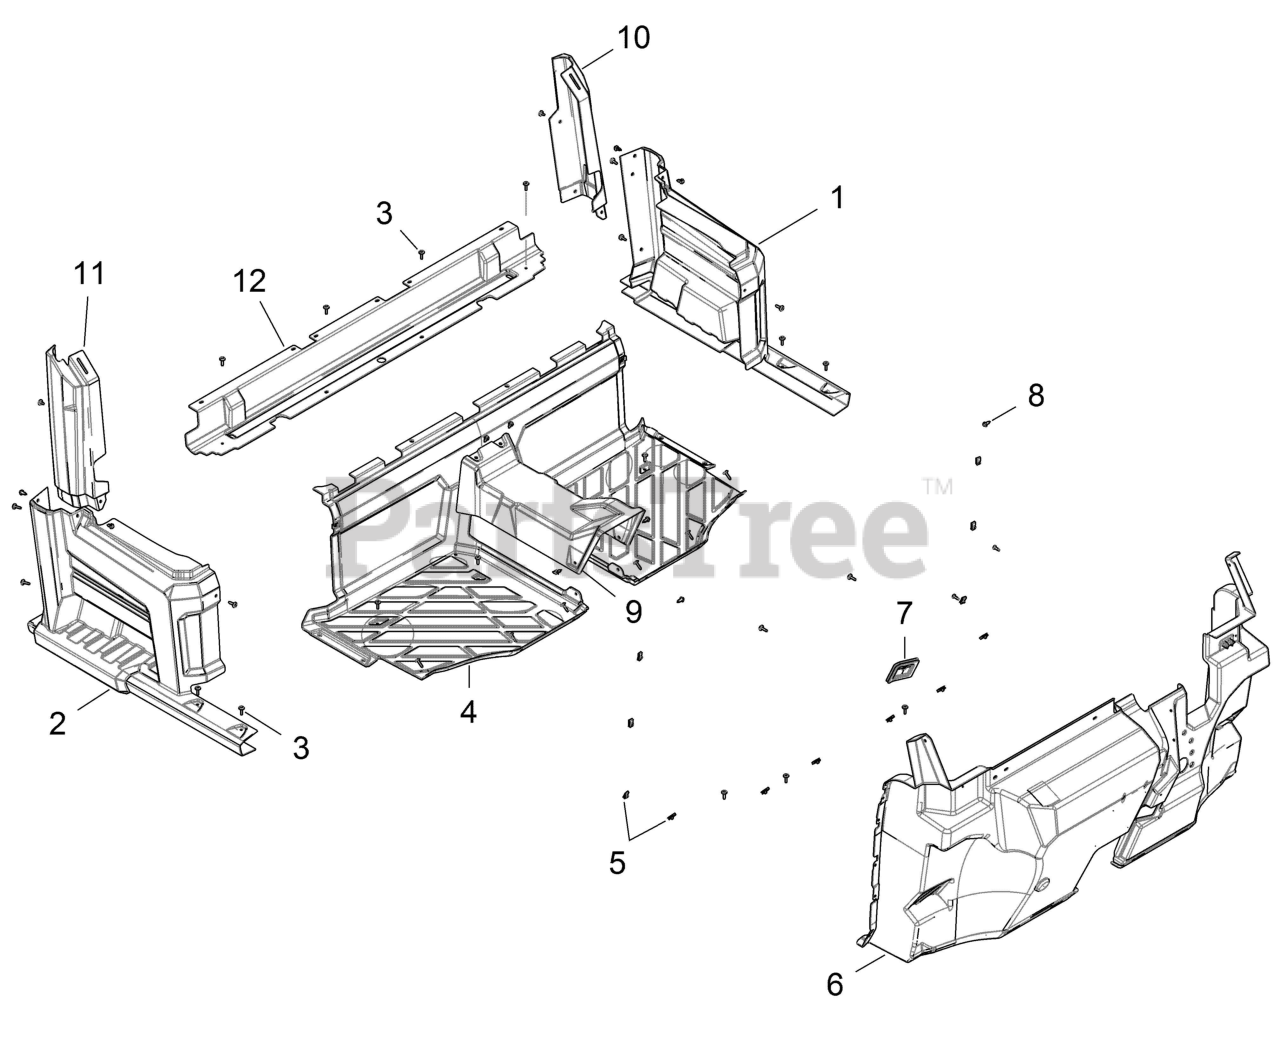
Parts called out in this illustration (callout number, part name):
1	FENDER, FRONT, W/ROCKER, LH
2	FENDER, FRONT, W/ROCKER, RH
3	SCR-TXTH-M6X1.0X25 RIE
4	FLOOR-BLK
5	CLIP-U SPEED NUT
6	FLOOR-FRONT,BLK
7	GROMMET-STEERING,FLOOR
8	RIVET-TUFLOK,.315-.325X.787 (5
9	COVER-DRIVE SHAFT,FLOOR,BLK
10	FENDER-REAR,UPPER,LH,BLK
11	FENDER-REAR,UPPER,RH,BLK
12	PANEL,CLOSEOFF CTR,ROUTER,BLK
